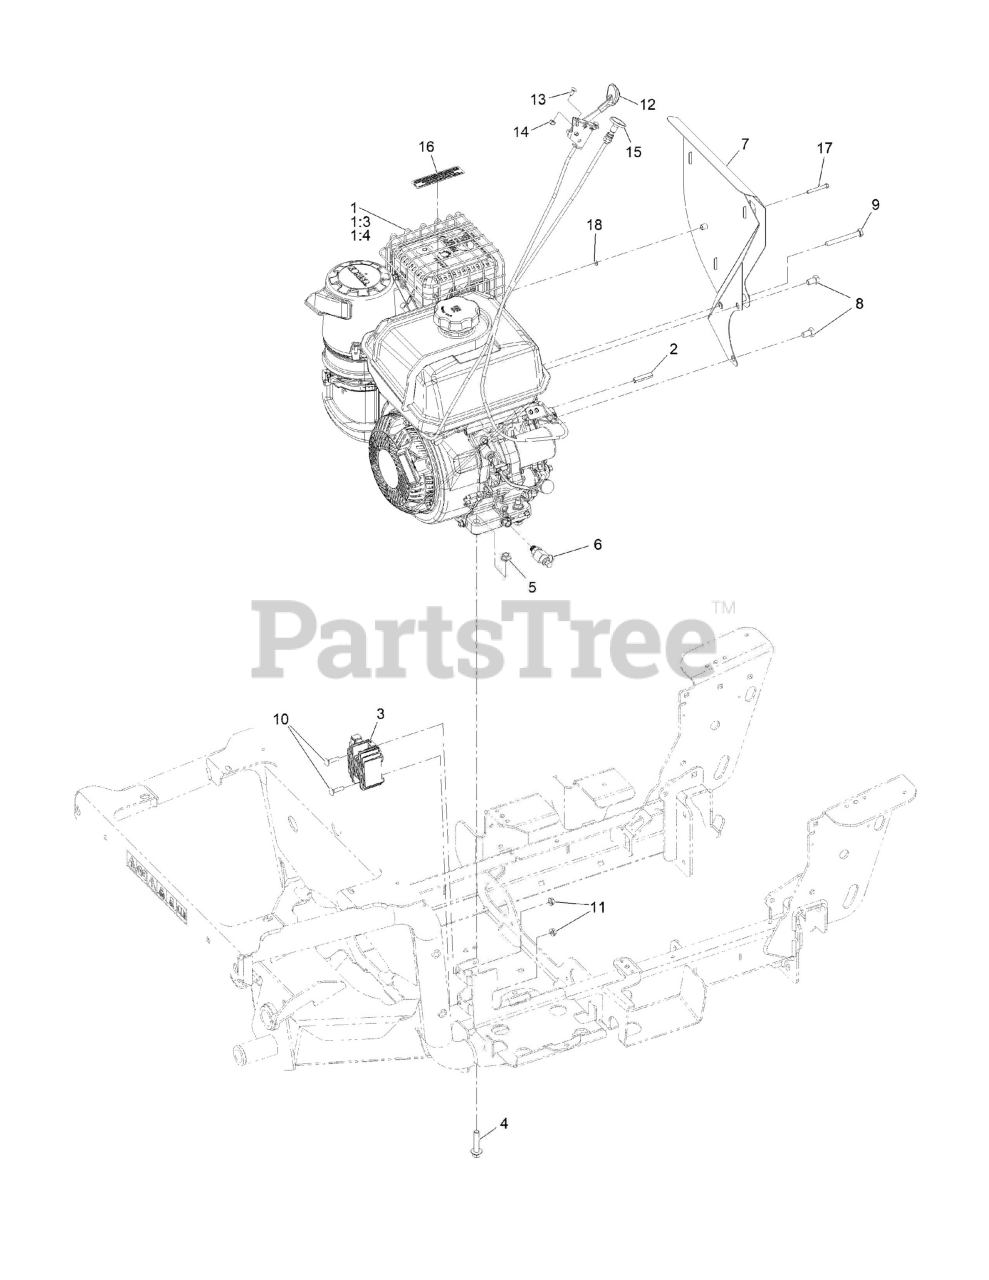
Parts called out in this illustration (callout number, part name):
1	Engine-Kohler, Ch395
1:3	Cage-Ch395 17_314_197 Bird
1:4	Deflector-Exhaust, Kohler
2	KEY-SQUARE, 7MM
3	REGULATOR-TROMBETTA, 18A
4	SCREW-HHF
6	Valve-Drain, Oil
7	HEAT SHIELD ASM
8	Screw-HH
9	Screw-HH
10	SCREW-CARR
12	Control-Throttle
13	BOLT-CARR
14	NUT-LOCK, NI
15	Cable-Choke, Push/Pull
16	DECAL-ARRESTOR, SPARK
17	BOLT-M5X0.8MM X 40 MM LON
18	WASHER-FLAT
